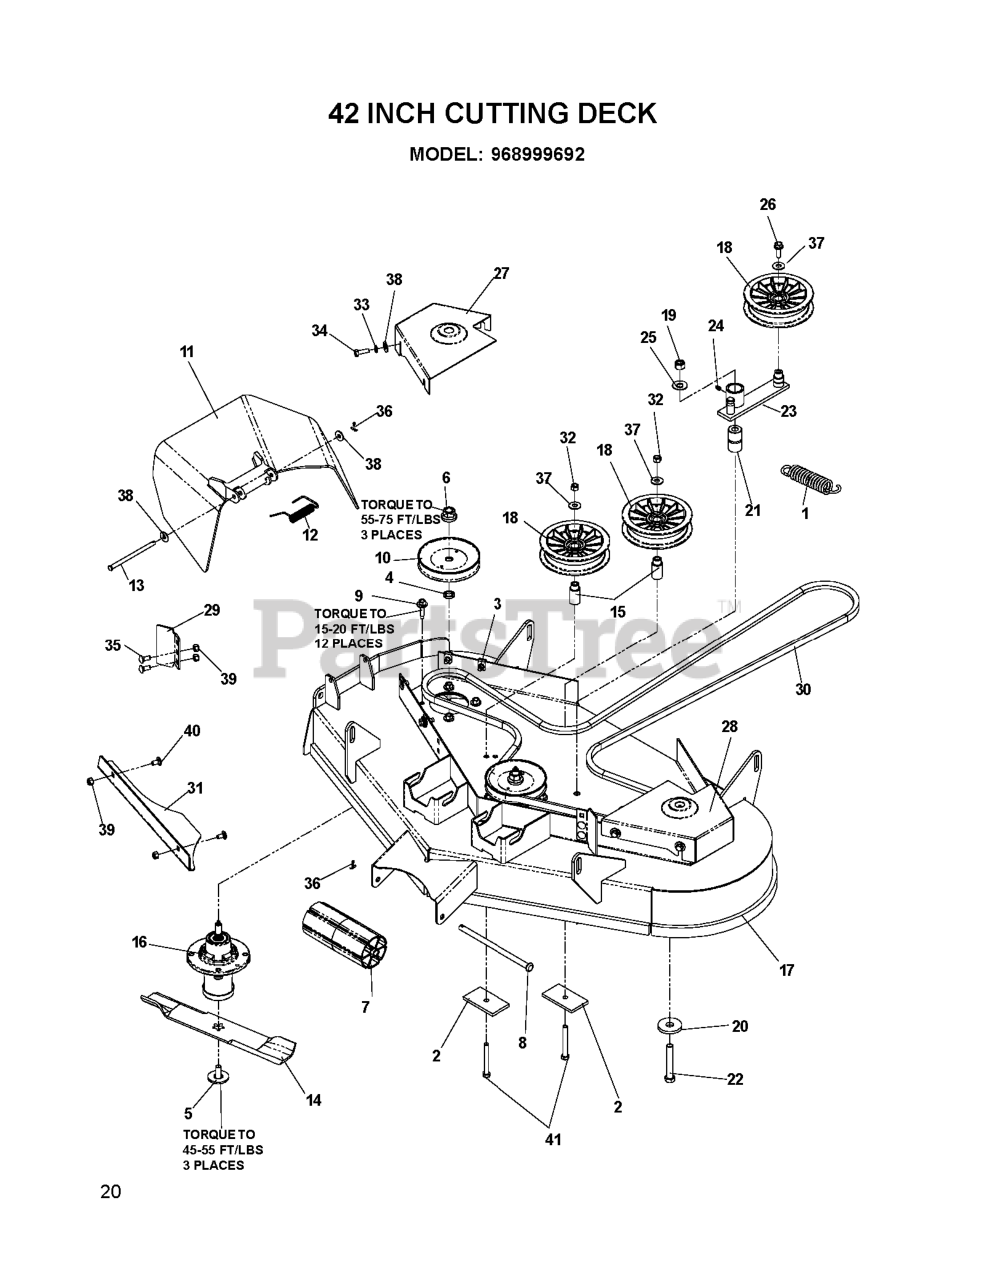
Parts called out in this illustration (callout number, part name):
2	SUPPORT PLATE
3	U-CLIP 5/16-18 NUT RETAINER
4	WASHER-SPACER
5	BLADE BOLT ASSY-7/16" TB REPL
6	LOCKNUT - 9/16
7	NOSE ROLLER 48"
8	NOSE ROLLER ROD
9	WASHER HEAD SCREW
10	PULLEY MANDREL
11	DISCHARGE CHUTE 42"
12	SPRING - TORSION
13	PIN-CLEVIS 5/16 DIA X 5.19 ZD
14	BLADE, 14 5/8"
15	IDLER BUSHING
16	MANDREL.DECK.ASSEMBLY
17	DECK W/DECALS 42"
18	IDLER
19	NUT 1/2-13 HEX NYLOC ZD
20	WASHER, SUPPORT
21	PIVOT BUSHING
22	HCS 1/2C X 3 1/4
24	ZERK
25	WASHER 1/2 FLAT
26	4CS 3/8C X 1 SERRATED HEAD
27	BELT SHIELD, RIGHT 42, ORG
28	BELT SHIELD, LEFT 42, ORG
30	BELT, DECK 42"
31	CONFINEMENT.PLATE.42".BLACK
32	NUT 3/8-16 NYLOC
33	WASHER.LOCK.HVY.HLCL.SPR.5/16
34	HCS 5/16C X 1
35	BOLT 5/16C X 3/4" CARRIAGE
36	RP_COTTER PIN 1/8 X 3/4
37	WASHER 3/8 FLAT
38	WASHER 5/16 FLAT
39	NUT 5/16 NYLOC
40	CARRIAGE BOLT 5/16C X 5/8"
41	HCS 3/8C X 3
